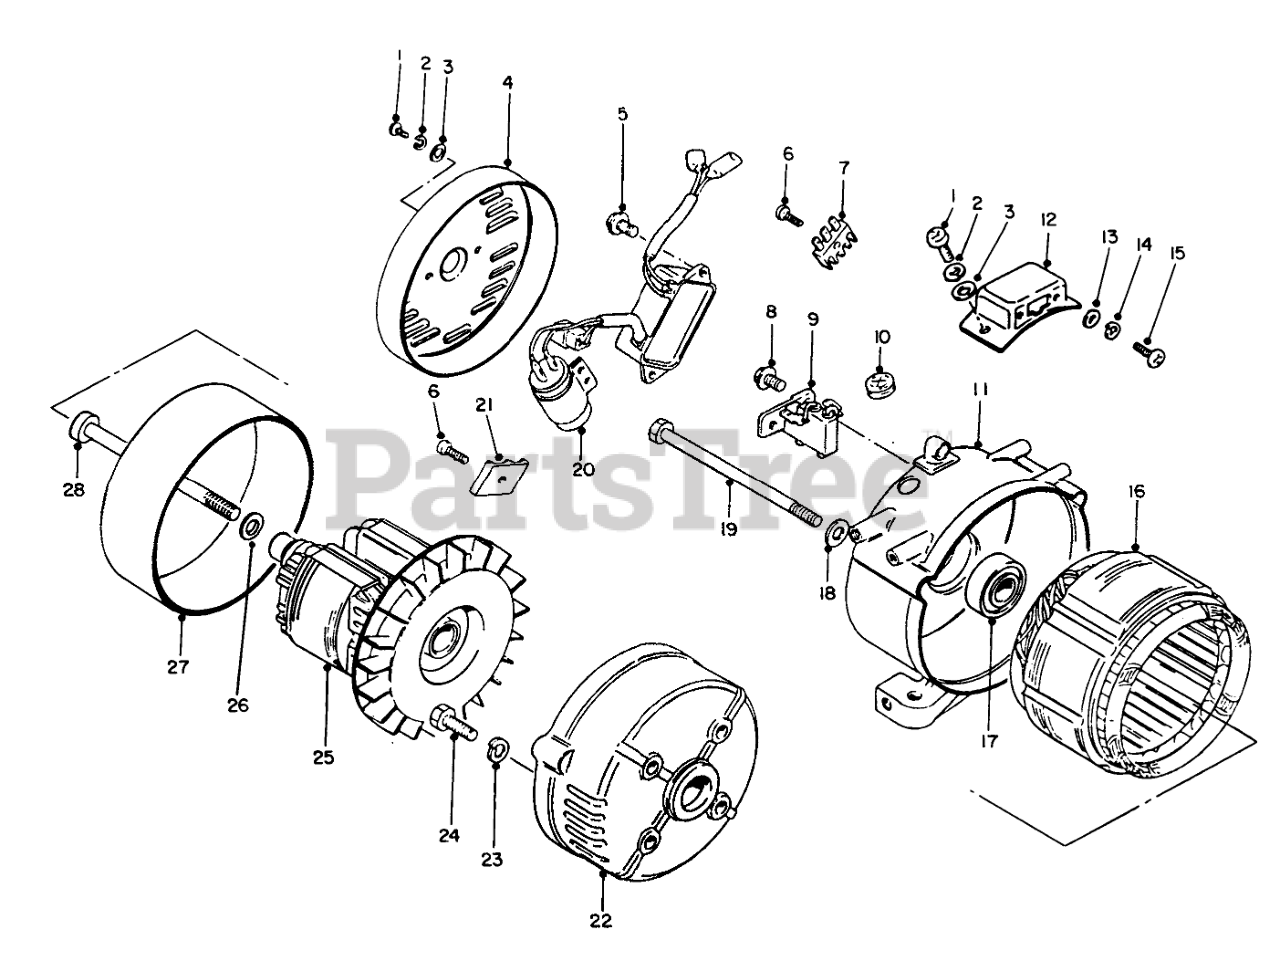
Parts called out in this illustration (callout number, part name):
1	SCREW
2	Washer
3	WASHER
4	REAR COVER
5	Bolt
6	Screw
7	Diode
9	HOLDER
10	Grommet
11	Bracket-Rear
12	Cover-Coupler
13	Washer
14	Lockwasher
15	SCREW
16	STATOR
17	Bearing
18	Washer
20	Regulator-Voltage
21	Terminal
22	Bracket-Front
23	Lockwasher
25	Rotor
26	Washer
27	Cover
